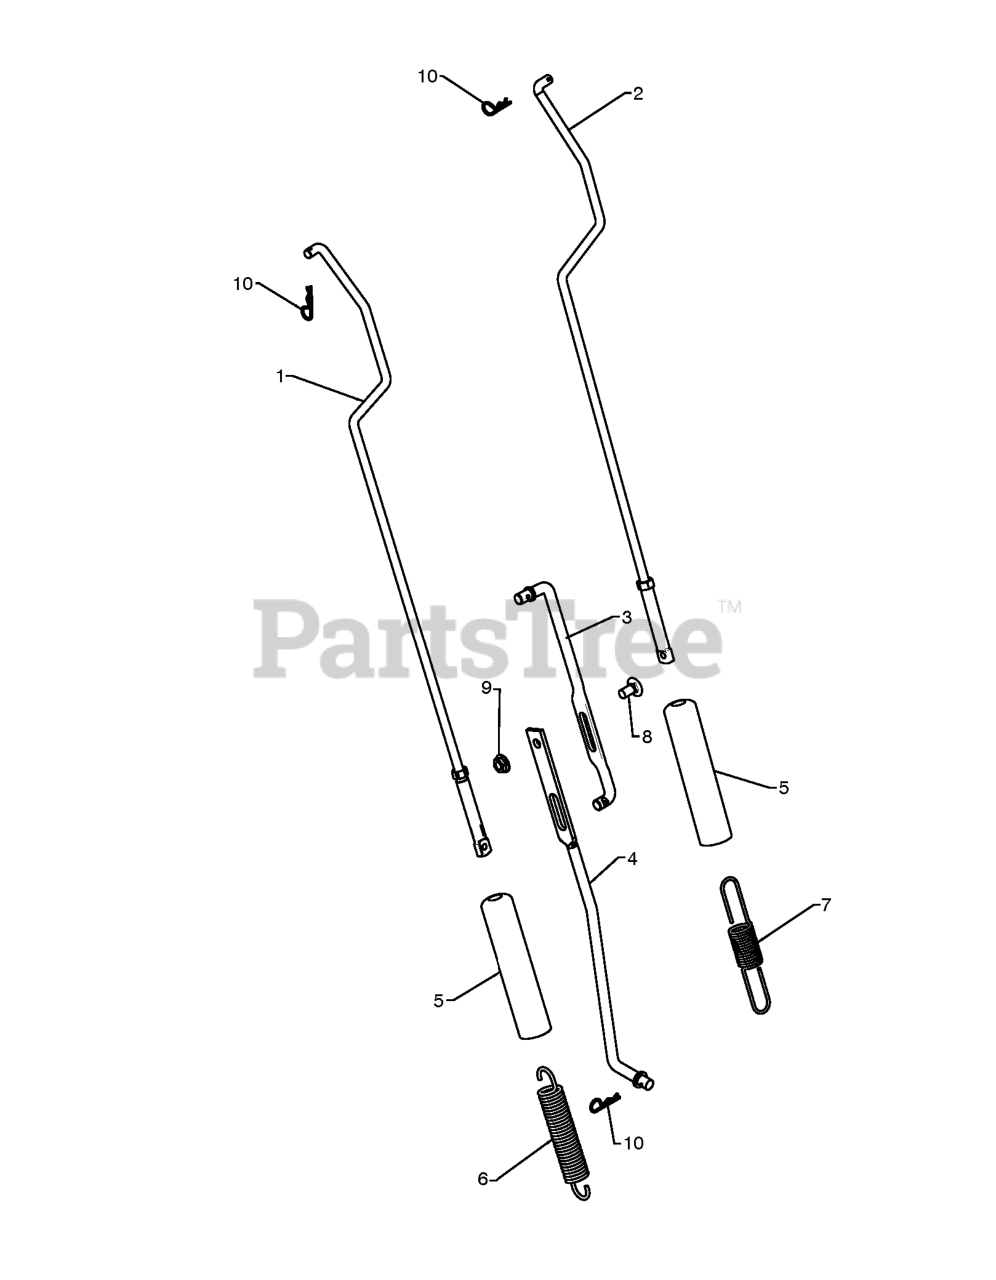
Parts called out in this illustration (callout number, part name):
1	ROD.ASM.IMPELLER
2	ROD.ASM.TRACTION
3	ROD, UPPER SPEED CONTROL
4	ROD, LOWER SPEED CONTROL.SNOW
5	SLEEVE, SPRING
6	SPRING, AUGER CONTROL
7	SPRING, TRACTION DRIVE
8	BOLT
9	NUT.FLANGE.5/16
10	SPRING RETAINER
